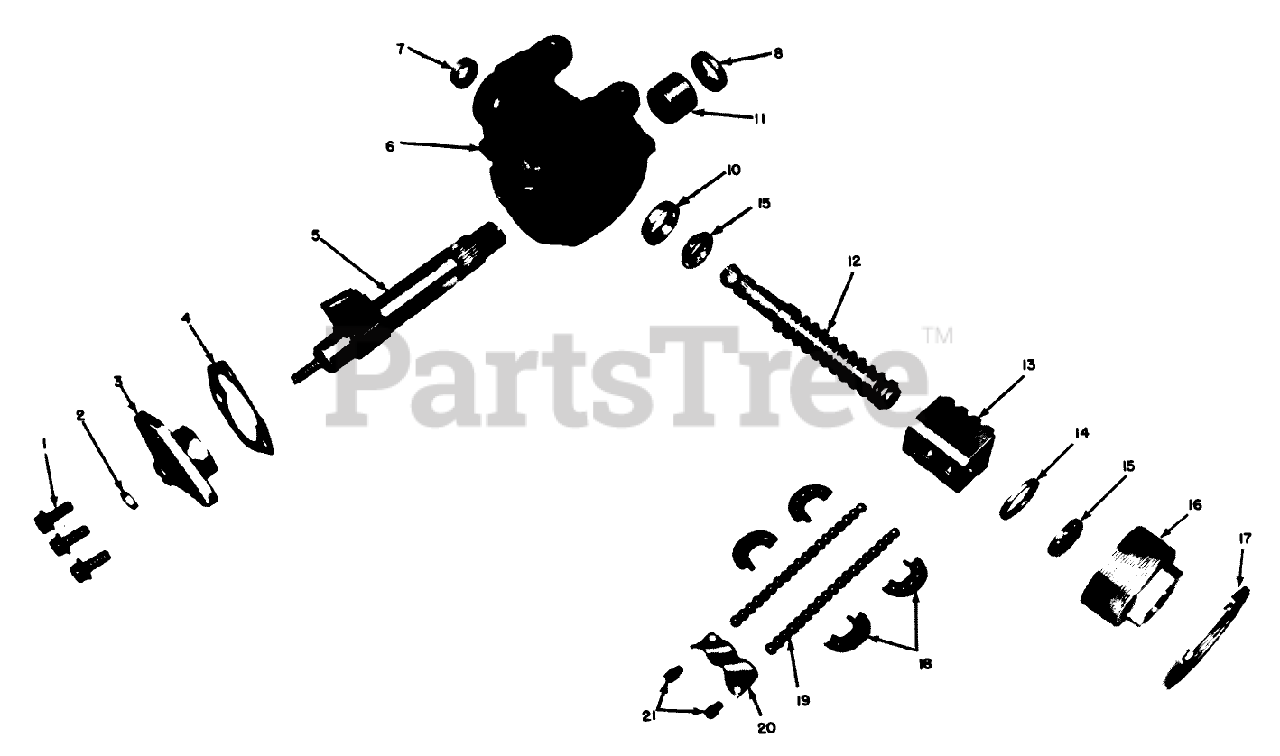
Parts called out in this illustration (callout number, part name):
1	Bolt Hexagon
2	Nut, Hexagon Jam 5/16-24
3	Cover Assy., Housing Side
4	Gasket, Housing Side Cover
5	Gear Assembly Pitman Shaft
6	Housing Assy., Steering Gear (Incl. Ref. #10 & 11)
7	Seal, Worm Shaft
8	Seal, Grease
10	Cup, Worm Thrust Bearing (Not available part of 7815600)
11	Bushing, Pitman Shaft
12	Worm Assy., Steering (Incl. Ref. #12, 13 & 18-21)
13	Nut, Bolt (Not available part of 7809767)
14	Retainer, Lower Bearing
15	Bearing Assy., Worm Thrust
16	Adjuster Assy., Worm Bearing (Incl. Ref. #14 & 15)
17	Nut, Lock
18	Guide, Ball Return
19	Clamp, Ball Return Guide
20	Clamp, Ball Return Guide
21	Screw Assembly & Lockwasher
